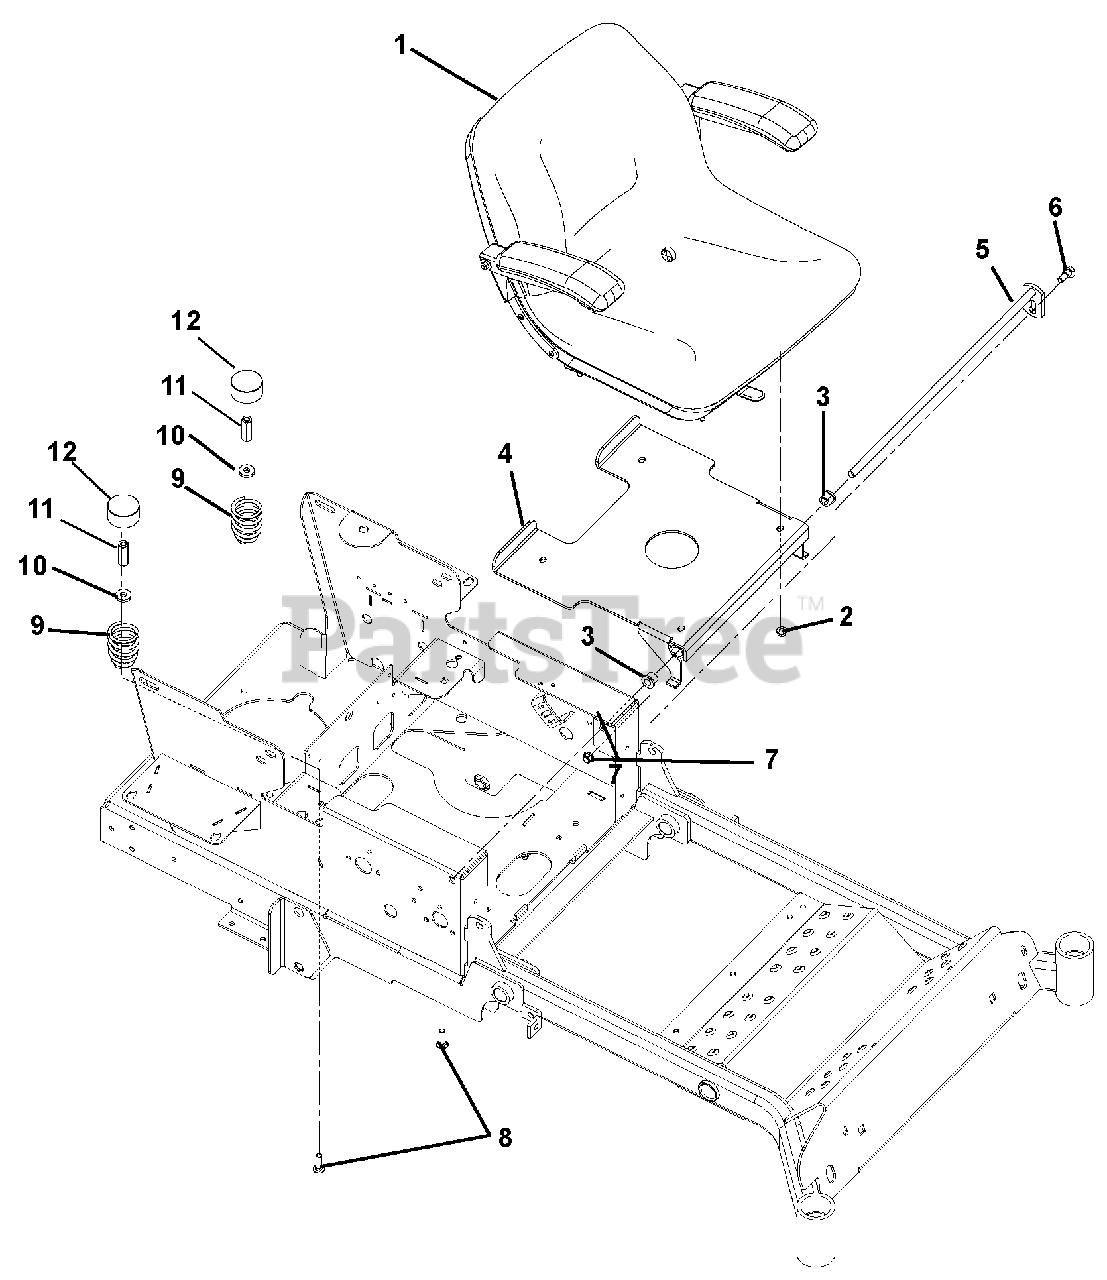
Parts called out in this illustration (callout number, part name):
1	SEAT, MILSCO XB-180
1	SWITCH- SNAP MTG N.O.
2	@NUT-LK-NYL-FLG .31-18 YWZC
3	BSHG, FLG .516X.750X.625X.937
4	WLDMT, SEAT PLATE
5	WMT, SEAT SHAFT
6	BLT,SHLDR EP .38-16X.30 HEX YZ
7	@NUT-SPNLK-FLG .375-16 YWZC
8	@BLT-RDHDSQNK .38-16X1.25 G5YZ
9	SPRING, SEAT
10	WSHR-FL-STL .406X1.00X.188 YWZ
11	NUT COUPLING .375-16X1.75
